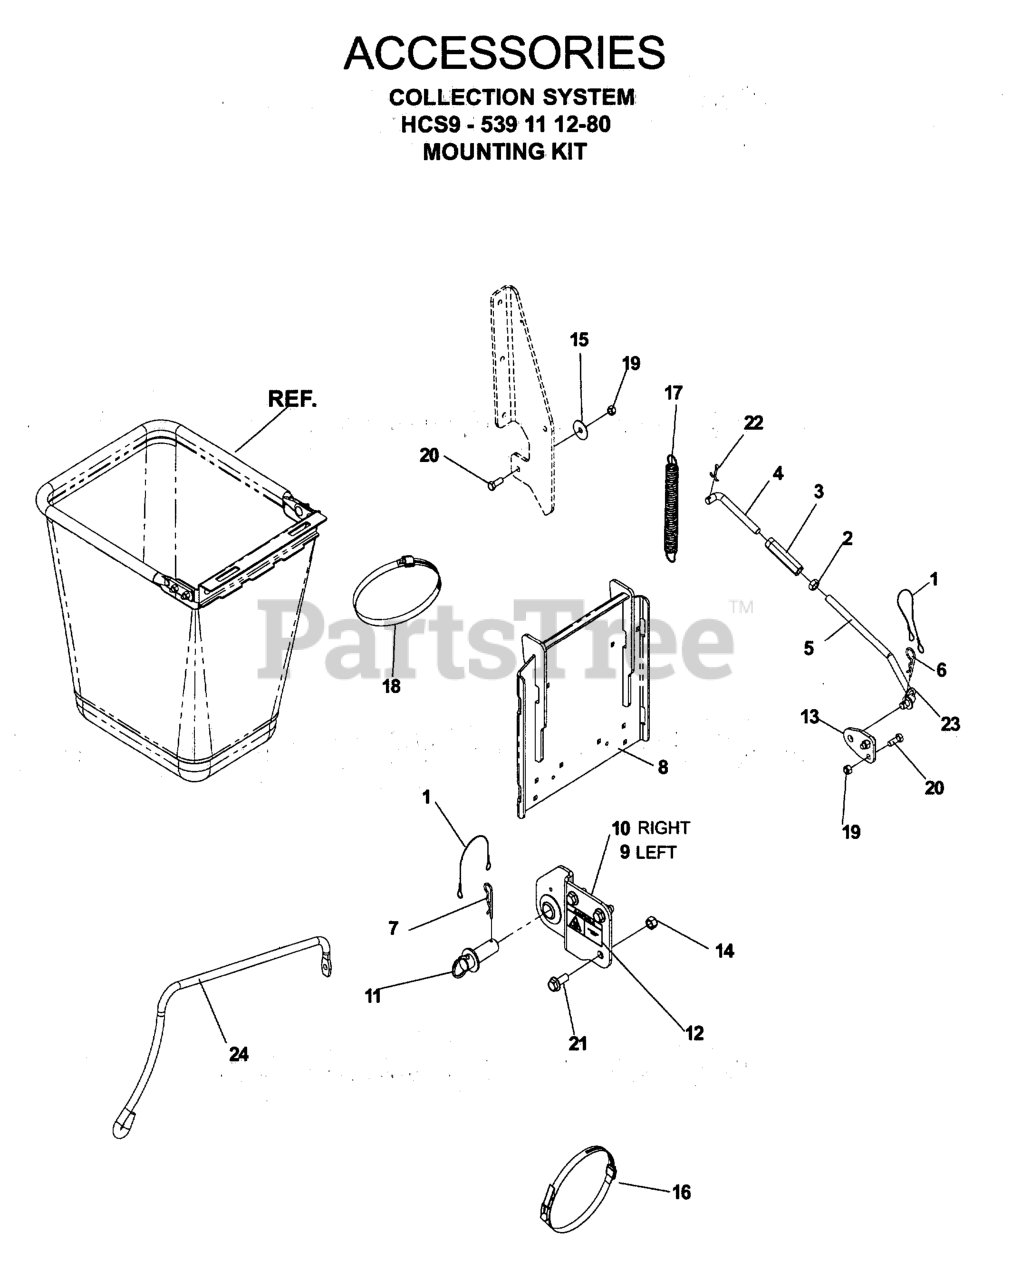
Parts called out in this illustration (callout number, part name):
2	NUT 1/2-20 HEX JAM ZD
3	TURNBUCKLE, 1/2
4	SUPPORT LINKAGE, LH
5	SUPPORT LINKAGE, MID
6	HAIRPIN #4
8	REAR GUARD WELDMENT
9	HITCH BRACKET WLD
10	HITCH BRACKET W/ DECAL MID
12	DECAL, HOT SURFACE
13	SUPPORT BRACKET
14	NUT 1/2-13 HEX NYLOC ZD
15	WASHER, FRICTION
16	OVER CTR BAND
18	HOSE CLAMP 4-1/8 TO 7"
19	NUT 3/8-16 NYLOC
20	HCS 3/8C X 1 1/2
21	HCS 1/2C X 1 1/4 SERRATED HEAD
22	COTTER PIN
24	HOSE SUPPORT
